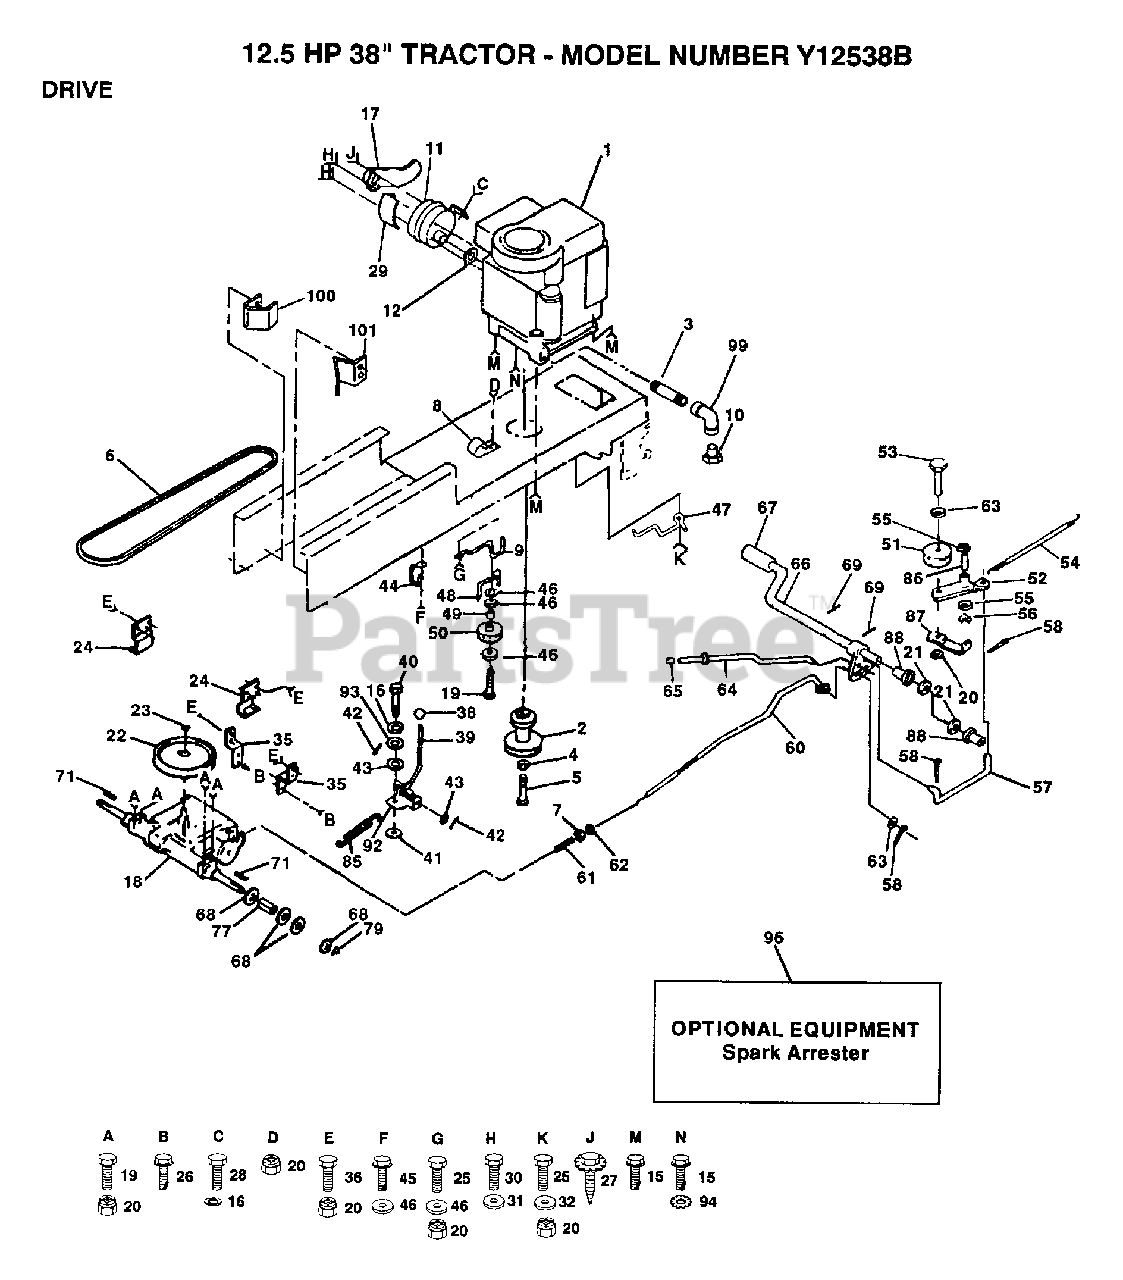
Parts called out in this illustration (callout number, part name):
3	PIPE NIPPLE
4	LOCKWASHER
5	BOLT
7	NUT
8	CLIP T
9	KEEPER.BELT.ENG.L
11	MUFFLER LTV
15	SCREW
16	LOCKWASHER
17	DEFLECTOR MUFFLER
19	BOLT
21	WASHER LT
22	PULLEY TRANS
24	BRACKET LT
25	BOLT
26	SCREW
28	BOLT
29	SHIELD HEAT LTV
30	"BOLT,HEX"
31	WASHER T
32	WASHER
35	STRAP TORQUE
38	KNOB T (1/2-HOLE)
39	ROD SHIFTER
41	WASH-SHFT PLT LT
42	PIN COTTER 1/8
43	WASHER
45	SCREW
46	WASHER
47	KEEPER BELT ENG
48	BELT KEEPER LT
49	SPACER T
50	PULLEY.IDLER.FLAT
52	ARM IDLER
54	"SPRING, RETURN LT"
55	WASHER LT
56	KLIP RING
57	"LINK, CLUTCH T"
58	COTTER PIN
61	SPRING ROD LT
62	NUT
63	WASHER
64	PARKING BRAKE ROD
65	PLUNGER CAP T
67	PEDAL COVER T
68	WASHER
71	SQUARE KEY
77	SPACER LT
79	E-RING LT
86	"LY, BEARING"
87	RETAIN BELT
88	NYLON BEARING
92	PLATE SHIFT LT
93	WASHER LT
94	LOCKWASHER
99	ELBOW
100	"KEEPER,BELT LH T"
101	"KEEPER,BELT RH T"
